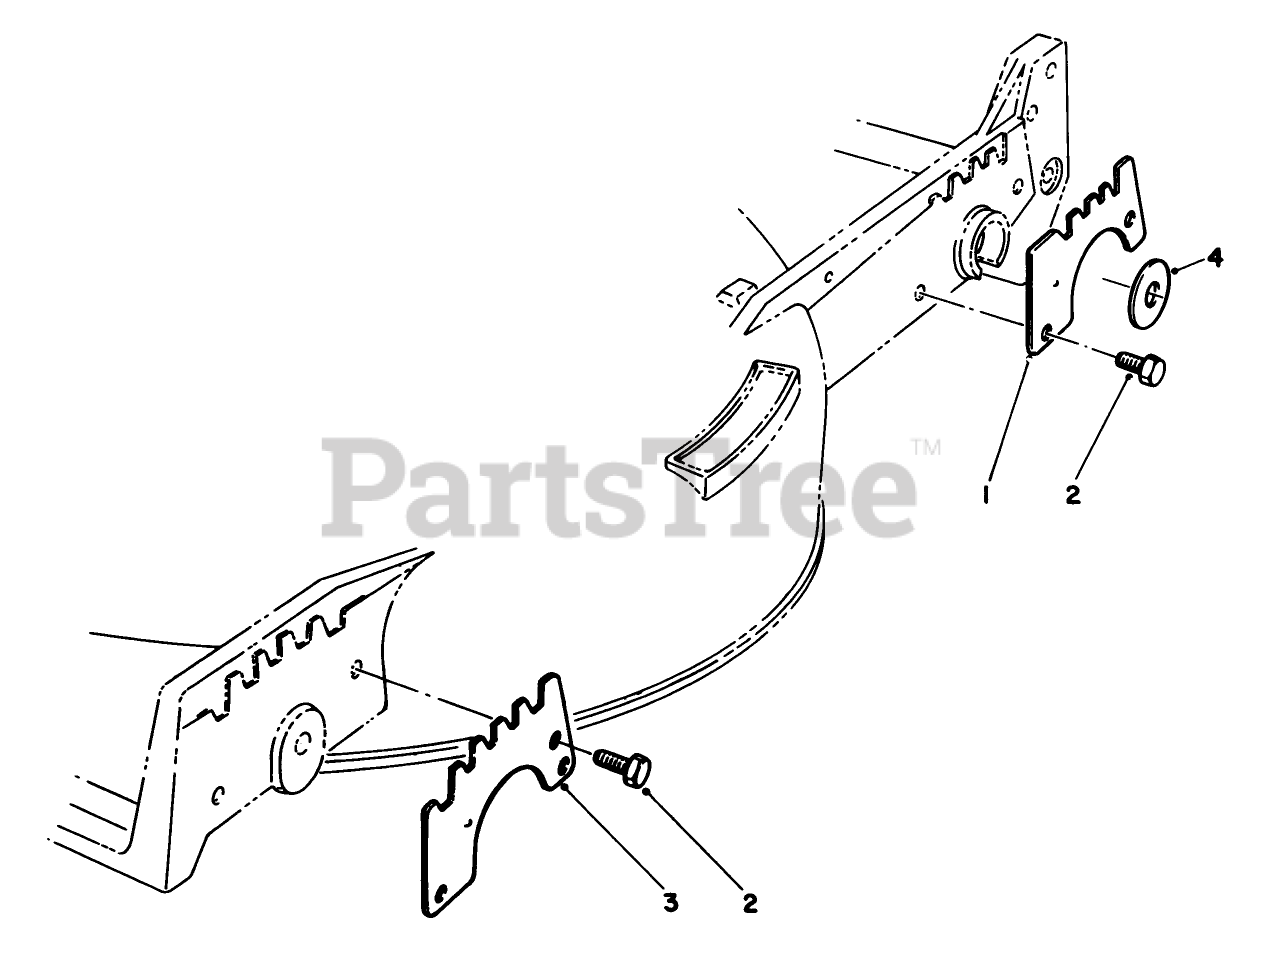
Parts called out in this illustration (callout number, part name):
1	WEAR PLATE,REAR
2	SCREW-HWH
3	WEAR PLATE
4	PIVOT WASHER
